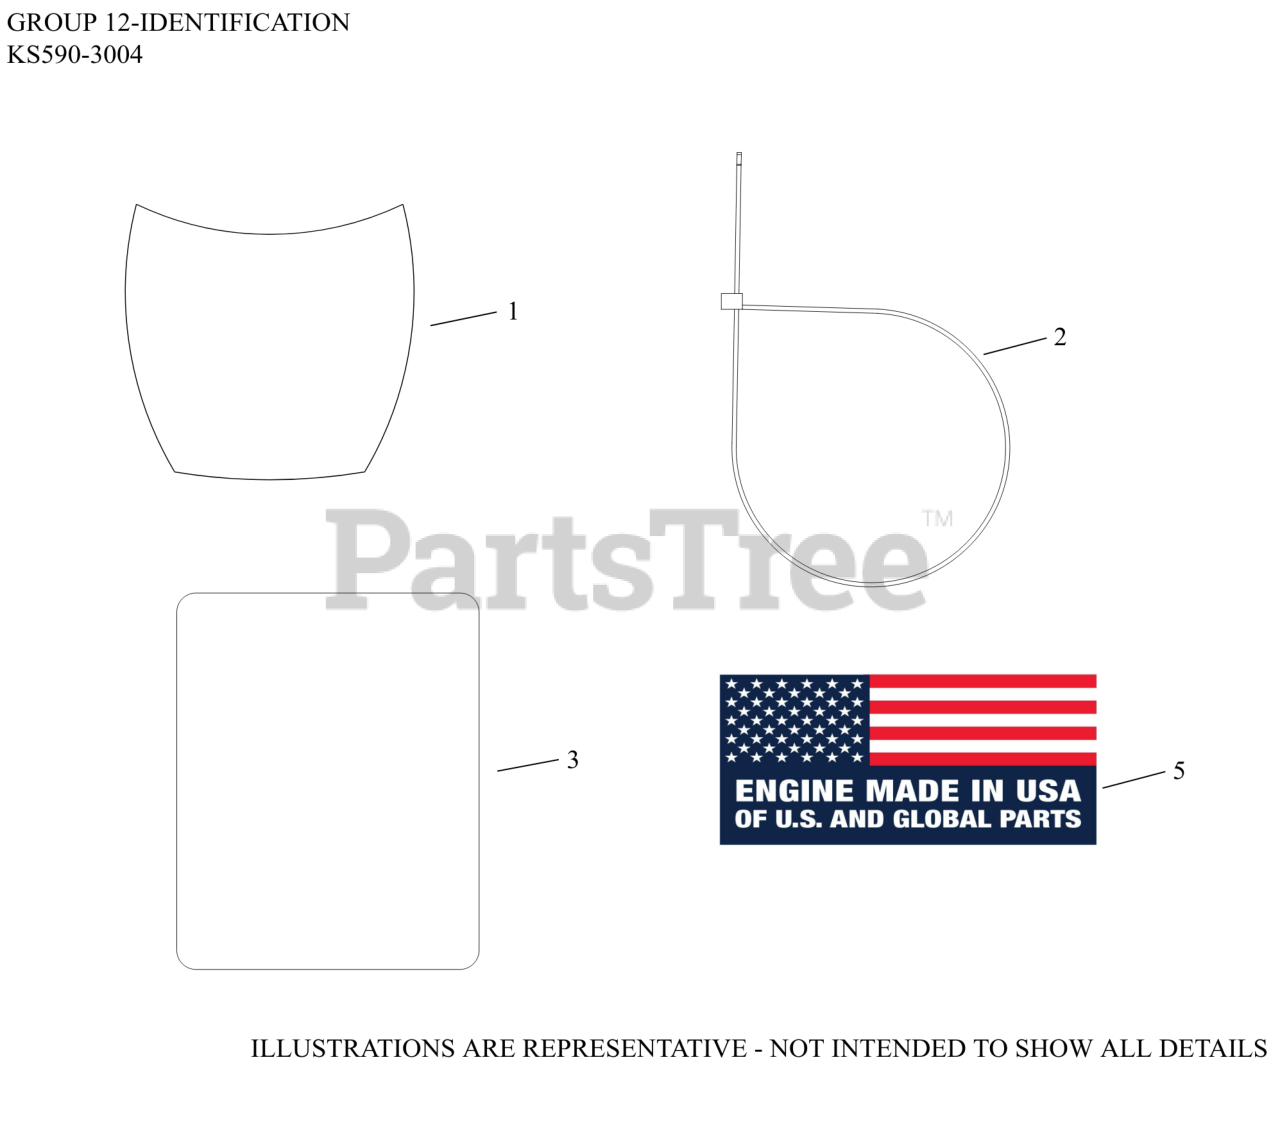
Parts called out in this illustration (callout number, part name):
1	LABEL, 19 HP STD AIR FILTER
3	LABEL, CLEAR LAMINATION
NI	DECAL, USA
